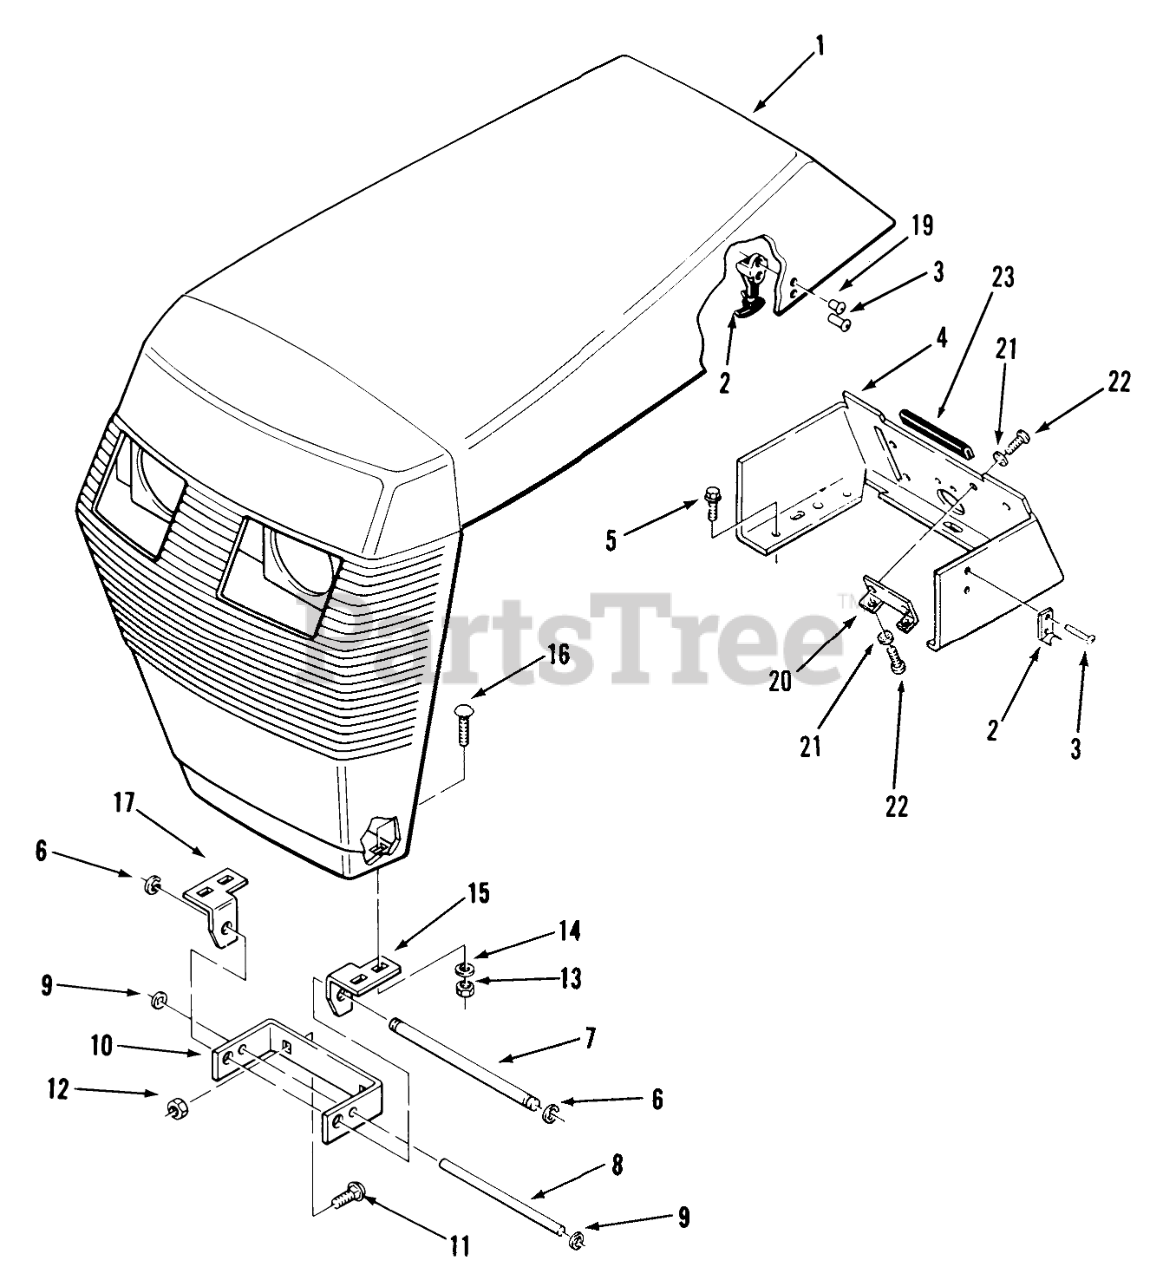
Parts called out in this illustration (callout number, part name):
1	Hood 208-3, 211-3, 211-5
2	ASSY-FLEX DRAW LATCH
3	RIVET -4
4	CONSOLE B
5	SCREW
6	RING-RETAINING
7	ROD-GRILL PIVOT
8	ROD-HOOD STOP
9	SPEED NUT
10	Bracket Hood Pivot
11	Bolt-Carriage
12	Nut
13	Nut
15	BRKT-GRILL PIVOT R (NS)
16	Bolt-Carriage
17	BRKT-GRILL PIVOT R
19	RIVET
20	Bracket 211-5, YT12A Only
21	Washer-Lock
22	Screw #6-32 x 3/8 Black
23	EDGING-CONSOLE
